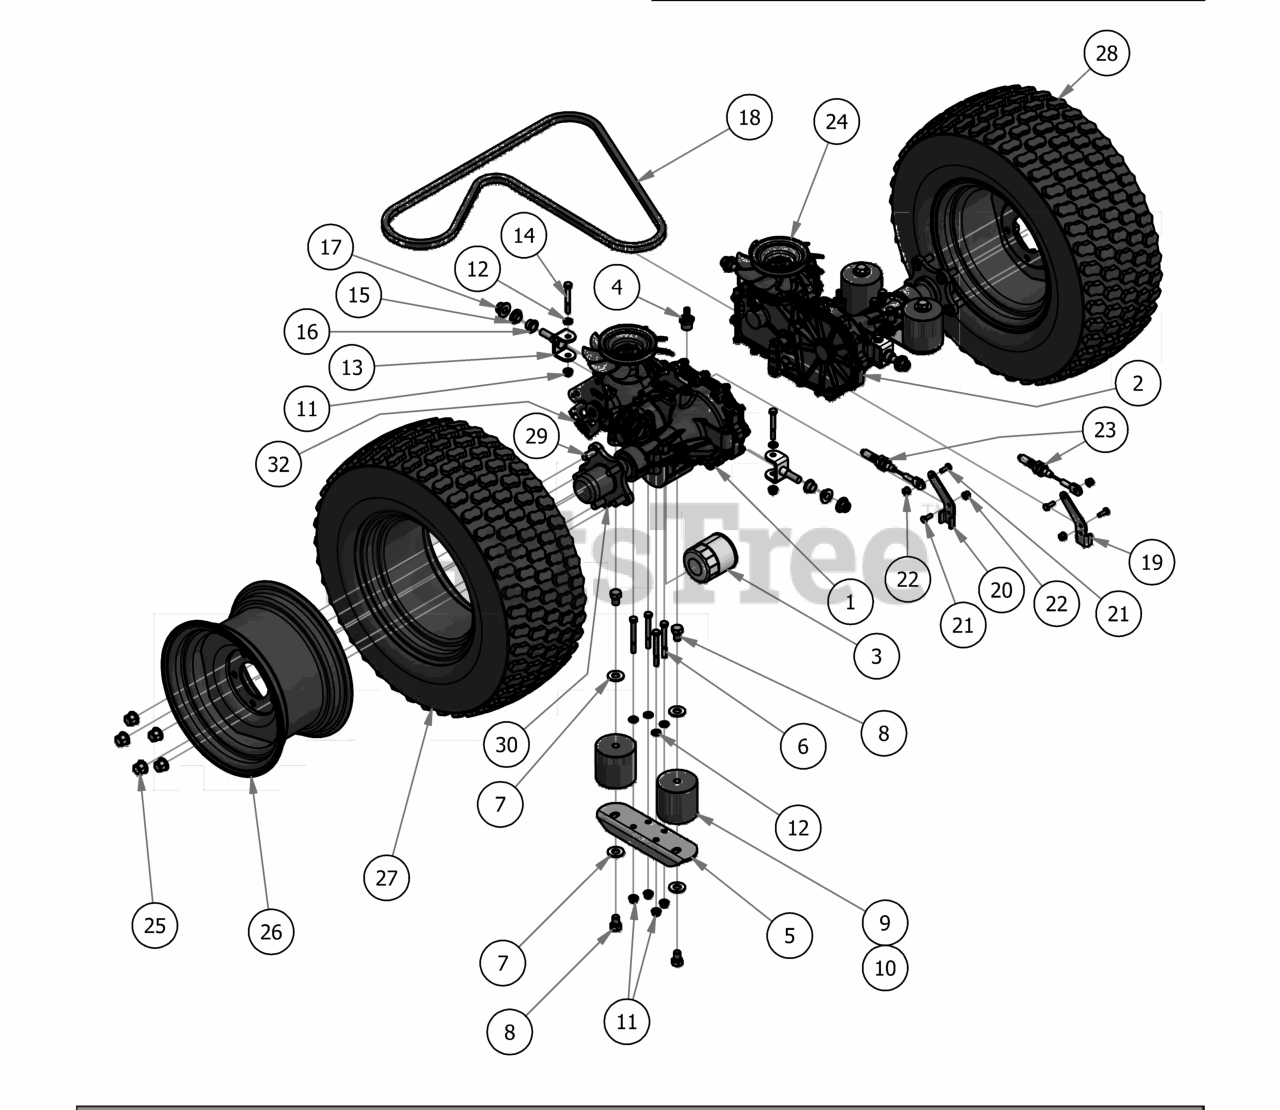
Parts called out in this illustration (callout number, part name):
1	3200 Left transaxle
2	3200 right transaxle
4	45 degree fitting
5	Rear Susp Transaxle Mount
6	5/16" x 3" Hex Bolt
7	1/2" Washer (Grade 8)
8	1/2" x 3/4" Hex Bolt
9	Vibration Mount-Green Dot
10	Vibration Mount-Red Dot (48" Maverick Only)
11	5/16" Flange Nut
12	5/16" Flat Washer
13	Maverick Rear Transaxle Pivot Bracket
14	5/16" x 2 1/2" Bolt
15	.515 ID Nylon Shoulder Washer
16	Bronze Bushing - SF - 2024-8
17	1/2-13 Nylon Flange Nut
18	75.8" Pump Belt
19	Brake Arm Ext (Right)
20	Brake Arm Ext (Left)
21	1/4" x 3/4" Hex Bolt
22	1/4-20 Nylon Insert flange Nut
23	Brake Cable
24	Fan/Pully Kit for ZT and Maverick
25	Acorn Lug Nut
26	12" Black Wheel
27	23 x 10.50 -12 Tire
28	Tire and Wheel Assembly (26 and 27)
29	Transaxle Hub
30	Transaxle Wheel Stud
32	Gold Transaxle Spring
